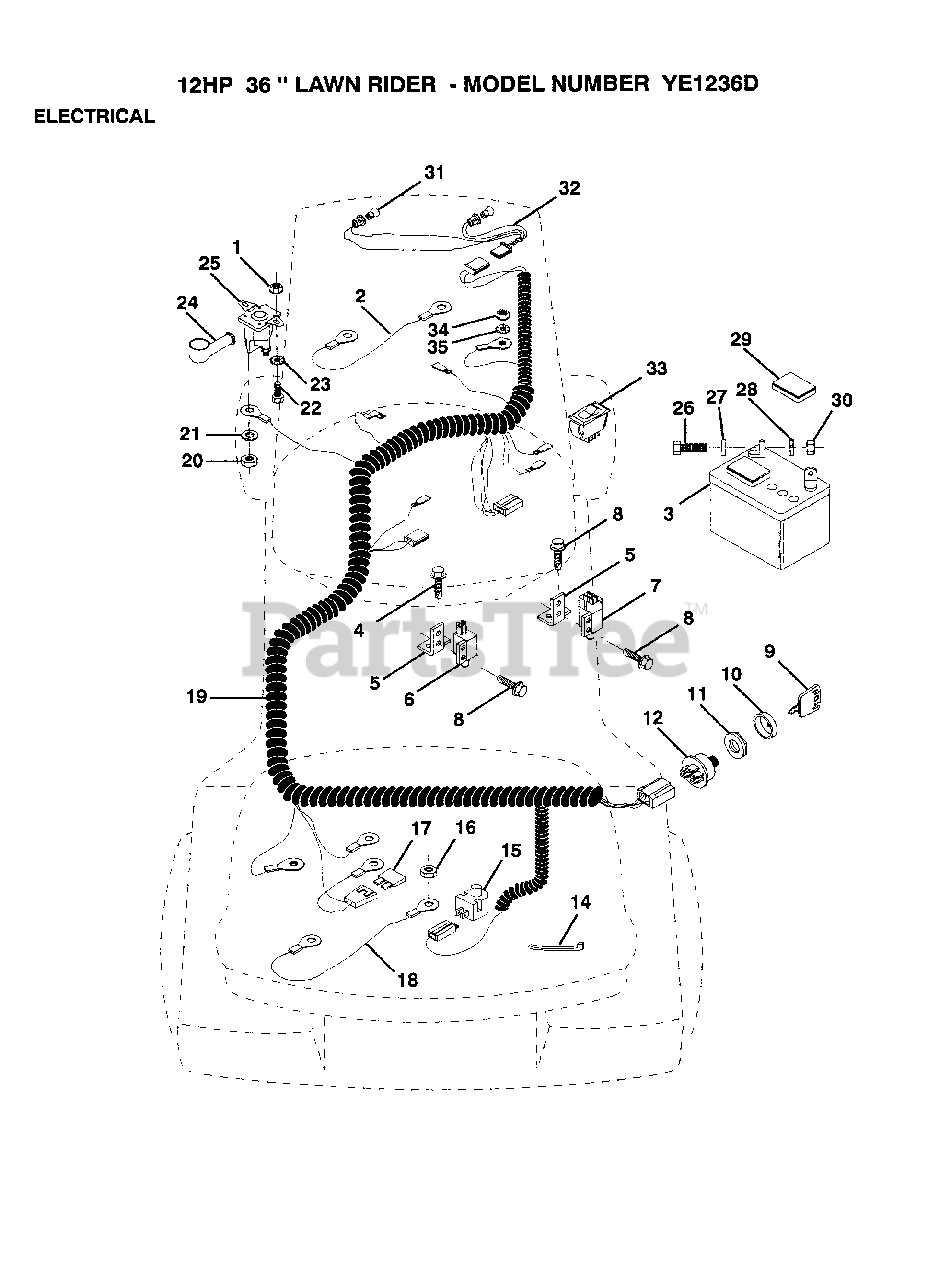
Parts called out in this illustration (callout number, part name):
1	NUT
2	CABLE ASM.
5	BRACKET LT
6	SWITCH-INTER. GT
7	SWITCH INTERLOCKT
8	SCREW
9	KEY
11	NUT IGNITION
14	WIRE TIE
15	SWITCH SEAT
17	FUSE HYT
18	CABLE ASSY
20	NUT
22	BOLT
26	BOLT LT
27	WASHER
28	LOCKWASHER
29	"CAP,BATTERY "
34	NUT
35	LOCKWASHER
